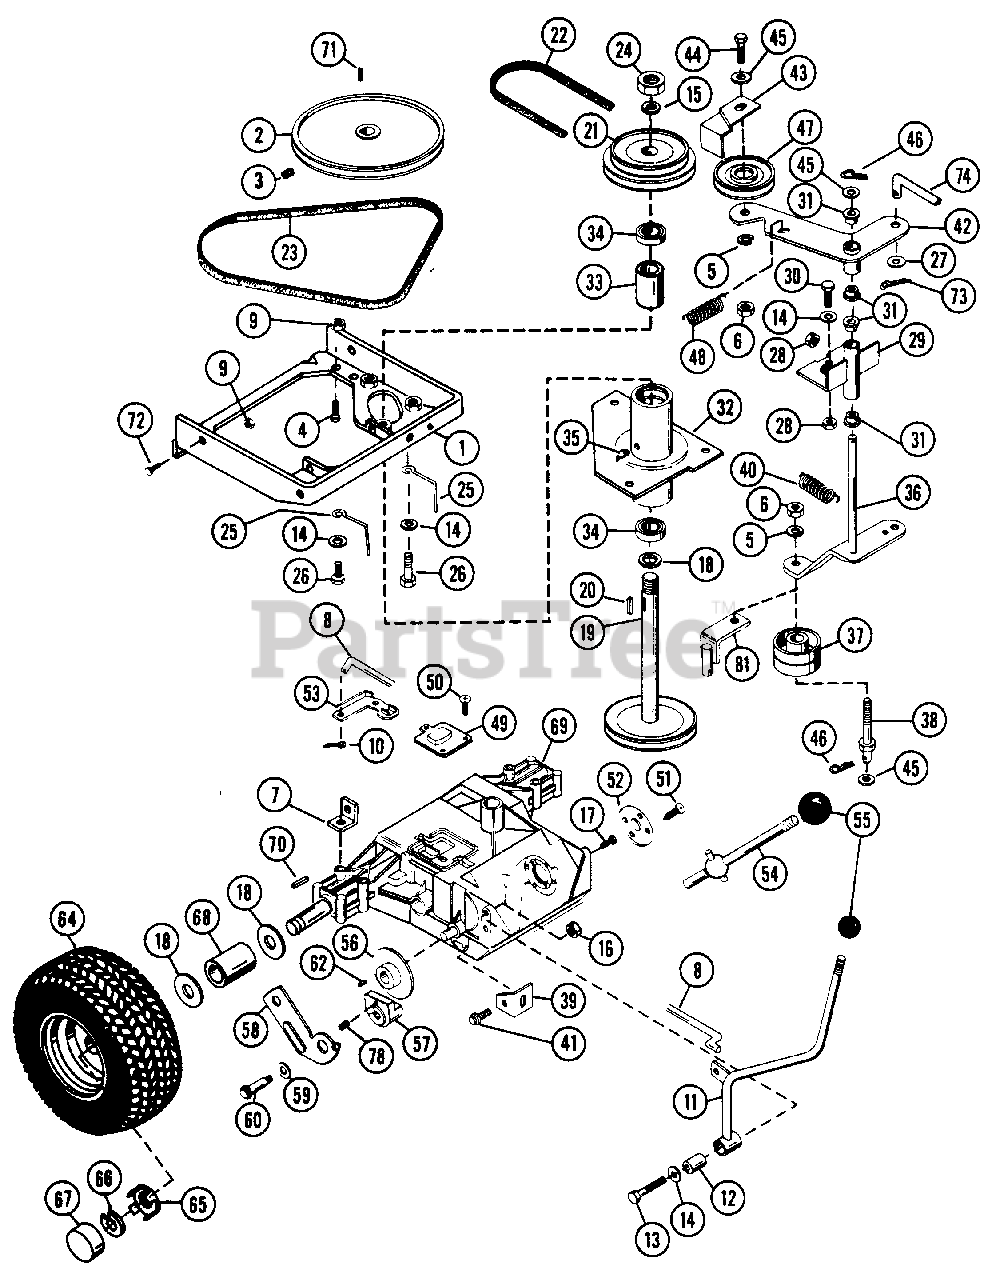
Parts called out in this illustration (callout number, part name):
1	TRANSAXLE MOUNT
2	TRANSAXLE SHEAVE
3	SCREW, SET 1/4-20X.375 HS CP
4	BOLT, HEX 3/8-16X2.75
5	WASHER, LOCK 3/8 REG.
6	NUT, HEX 3/8-16
7	TAB
8	SELECTOR ROD
9	NUT, LOCK 3/8-16
10	PIN, COTTER .09X.75
11	RANGE SELECTOR LEVER
12	SPACER
13	BOLT, HEX 1/4-20X2
14	WASHER, FLAT .312X.734X.065
15	LOCKWASHER, INTERNAL 3/4"
16	NUT, LOCK 1/4-20
17	BOLT, HEX 1/4-20X1.00
18	WASHER, FLAT .750X1.25X.125
19	JACKSHAFT SPINDLE
20	KEY, STRAIGHT SAE 1035
21	SHEAVE(PTO)(3) GROOVE
22	MAIN DRIVE BELT
23	TRACTION BELT
24	NUT, LOCK 3/4-10
25	BELT FINGER
26	BOLT, HEX 5/16-18X1.00
27	WASHER, FLAT .438X1.000X.083
28	NUT, LOCK 5/16-18
29	IDLER PIVOT
30	BOLT, HEX 5/16-18X.75
31	FLANGE BUSHING
32	SPINDLE HOUSING
33	SPACER
34	BEARING
35	ZERK FITTING
36	IDLER ARM
37	ATTACHMENT IDLER
38	IDLER MTG. BOLT
39	SPRING ANCHOR
40	DRIVE SPRING
41	BOLT, HEX 5/16-18X.50
42	IDLER ARM
43	BELT RETAINER
44	BOLT, HEX 3/8-16X1.75
45	WASHER, FLAT .406X.812X.065
46	HAIR PIN, INTERNAL 3/32X1-3/16
47	MAIN IDLER
48	EXTENSION SPRING
49	HI-LO COVER PLATE
50	SCREW, MACHINE 8-32X.5
51	SCREW, MACHINE 10-24X.50
52	COVER
53	HI-LO SHIFT LEVER
54	SHIFT LEVER ASSEMBLY
55	SHIFT BALL
56	BRAKE DISC
57	BRAKE JAW ASSEMBLY
58	LEVER, ACTUATING ASSEMBLY
59	WASHER
60	SHOULDER BOLT
62	KEY, WOODRUFF 3/16X5/8 HRD #61
64	TIRE AND WHEEL ASSEMBLY
65	SPINDLE CUP
66	"E" RING
67	HUB CAP
68	SPACER
69	TRANSAXLE
70	KEY, STRAIGHT 3/16X3/16X2
71	KEY, WOODRUFF 3/16X3/4 #9
72	BOLT, HEX 3/8-16X1.00
73	PIN, COTTER .125X1.00
74	CLUTCH ROD
78	SETSCREW, NO. 8-32
81	BRACKET
